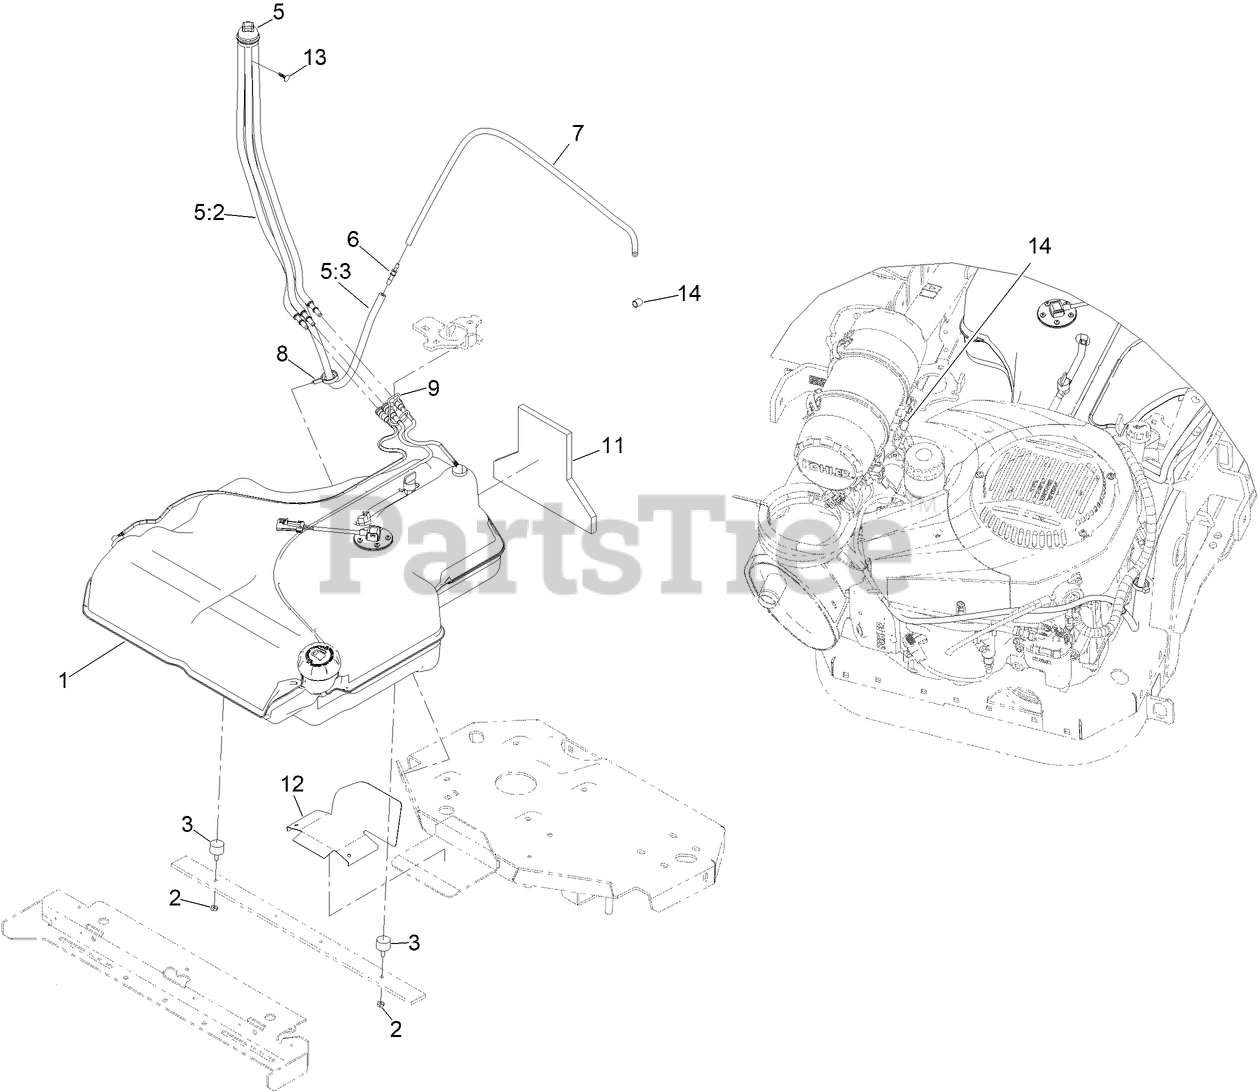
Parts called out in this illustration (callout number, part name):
1	FUEL TANK ASM
2	NUT-JAM
3	BUMPER
5	FUEL MANIFOLD VENT ASM
5:2	HOSE-FUEL
5:3	HOSE-FUEL
6	BARB-FUEL
7	HOSE-FUEL
8	CLAMP-HOSE
9	RETAINER-LINE, VAPOR
11	INSULATION-FOAM, FUEL TANK
12	GUARD-EXHAUST
13	PLUG-PLASTIC
14	PLUG-PORT
